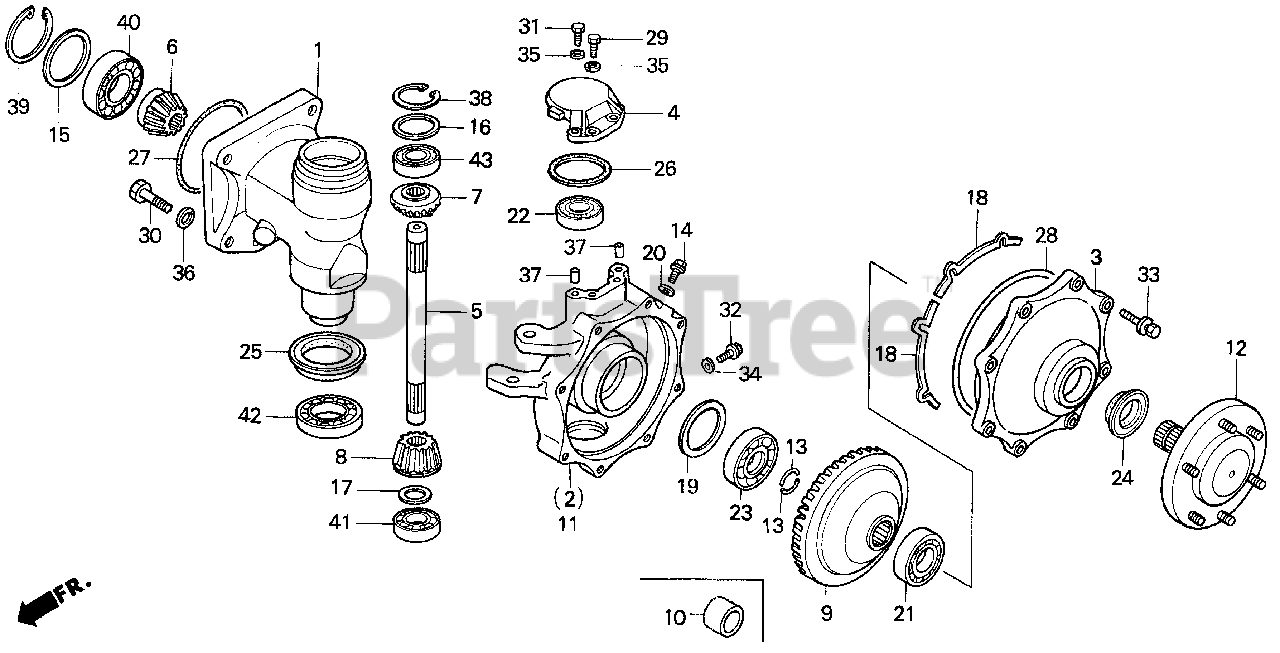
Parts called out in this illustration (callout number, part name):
1	CASE A, FINAL REDUCTION
2	CASE B, R. FINAL REDUCTION
3	COVER, FINAL REDUCTION
4	PIVOT, FINAL REDUCTION (UPPER)
10	COLLAR, FR. AXLE SHAFT
11	CASE B, L. FINAL REDUCTION
12	SHAFT, FR. AXLE
13	KEY, AXLE SHAFT LOCK
14	BOLT, DRAIN PLUG
20	WASHER, DRAIN PLUG (10.2MM)
21	BEARING (72X35X17) (NTN CORP.)
22	BEARING, RADIAL BALL (60/28)
23	BEARING, RADIAL BALL (62/32SP)
24	SEAL, WATER (42X62X13.5)
25	SEAL, WATER (50X70X20)
26	OIL SEAL (60X70X5)
27	O-RING (85.4X3.1)
28	O-RING (169.4X3.1) (NOK)
29	BOLT, HEX. (10X25)
30	BOLT, HEX. (12X40)
31	BOLT, HEX. (10X40)
32	BOLT, DRAIN PLUG (12MM)
33	BOLT-WASHER (8X32)
34	WASHER, DRAIN PLUG (12MM)
35	WASHER, SPRING (10MM)
36	WASHER, SPRING (12MM)
37	PIN, KNOCK (12X16)
38	CIRCLIP (INNER) (52MM)
42	BEARING, RADIAL BALL (6008UU)
